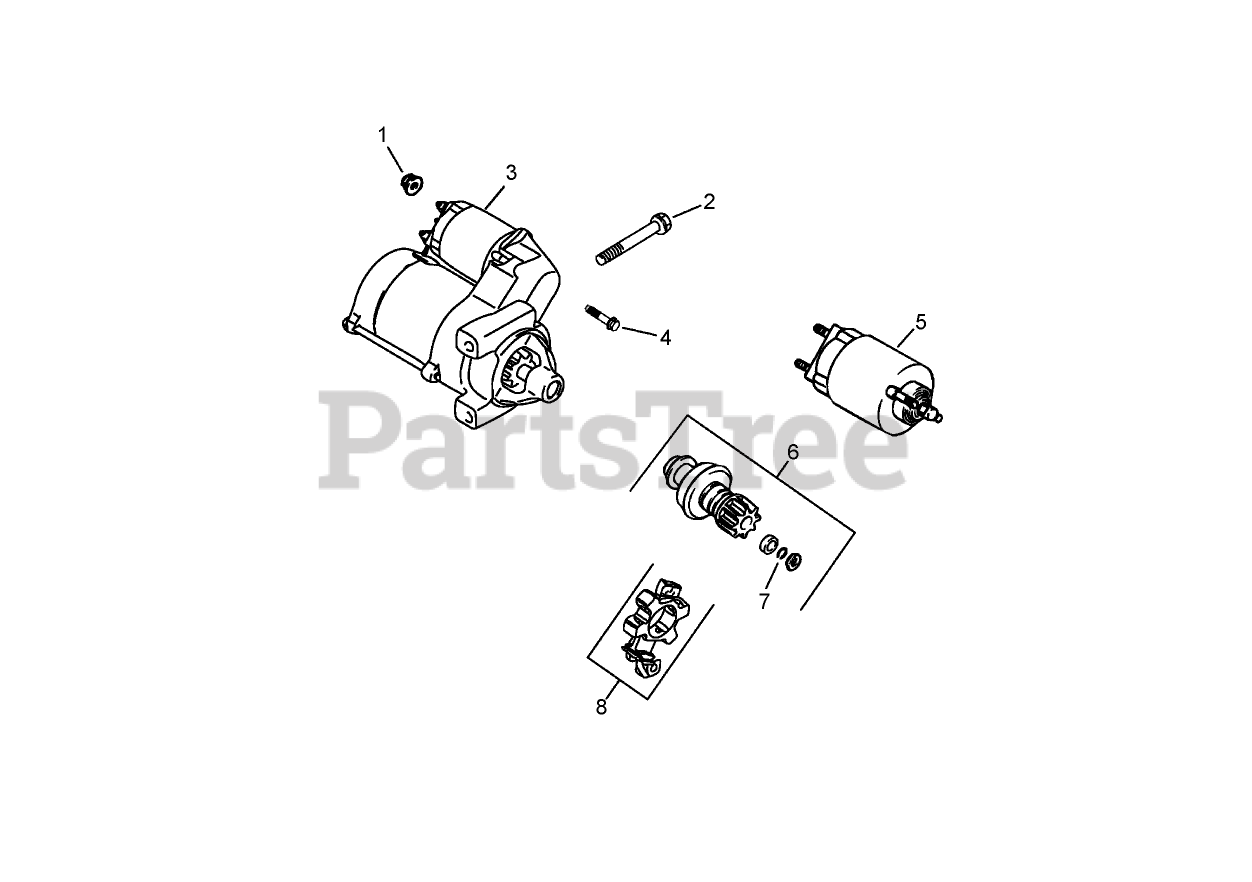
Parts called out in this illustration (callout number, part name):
1	NUT-FLANGE (M8X1.25)
2	SCREW-FLG (M8X1.25X80)
3	Starter Solenoid Shift ASM (Includes 4-8)
4	SCREW-TORX HEAD, EXTERNAL
5	Solenoid Kit (Includes 4)
6	Pinion Drive Kit (Includes 7)
7	RING-RETAINING
8	BRUSH HOLDER KIT
